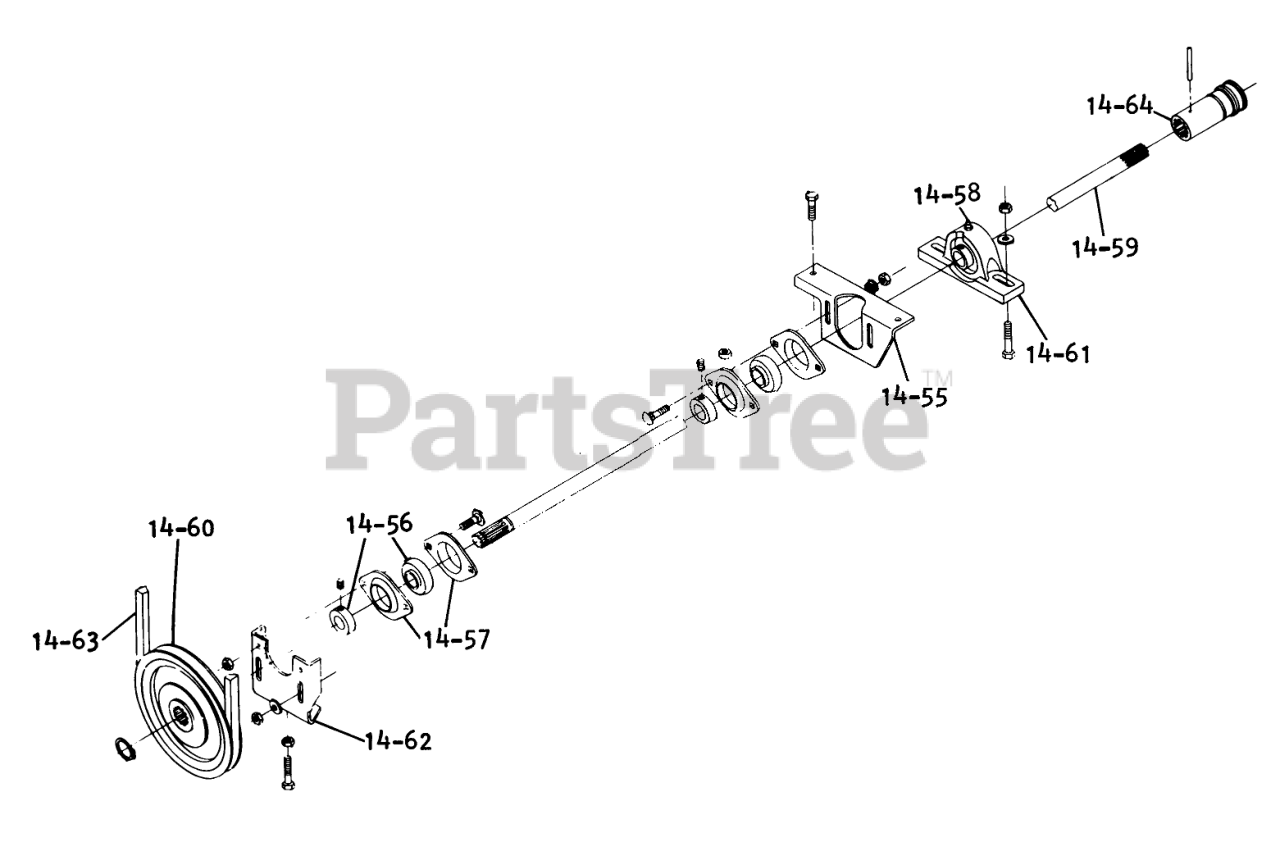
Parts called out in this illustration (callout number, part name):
14-55	Bracket
14-56	BEARING
14-57	FLANGE
14-58	ZERK 90DEGREE
14-59	SHAFT-DRIVE
14-60	Pulley
14-61	Assembly Bearing
14-62	Bearing Bracket
14-63	BELT PTO
14-64	QUICK COUPLER ASSY
15-01	Seat, D-160
15-02	Plate Seat Pivot
15-03	Bracket-Pivot RH
15-04	Bolt
15-05	Bushing
15-06	BUMPER-RUBBER
15-07	Spring
15-08	Seat Pivot Assembly
15-09	Seat Adjustment Assembly
15-10	SPACER
15-11	Rod-Adjusting
15-12	Rod-Pivot
15-13	Spring
15-14	Bar-Seat Stop
15-15	Seat Ad justing Plate
15-16	Seat Base
15-17	Seat Cushion
15-18	Back Cushion
15-19	Wing Head Stud
15-20	Decal
15-21	Decal-"D-160 Automatic"
15-22	Decal-Tach-a-matic
15-23	Decal
15-24	Decal-Clutch Knob
15-25	Sleeve
15-26	Decal
15-28	Decal-Caution
15-29	Decal
15-30	Decal-Maintenance
15-31	Reflector
15-32	Seat Plate, D-200
15-33	Seat
15-34	Arm Rest-R.H.
15-35	Decal-Parking Brake
